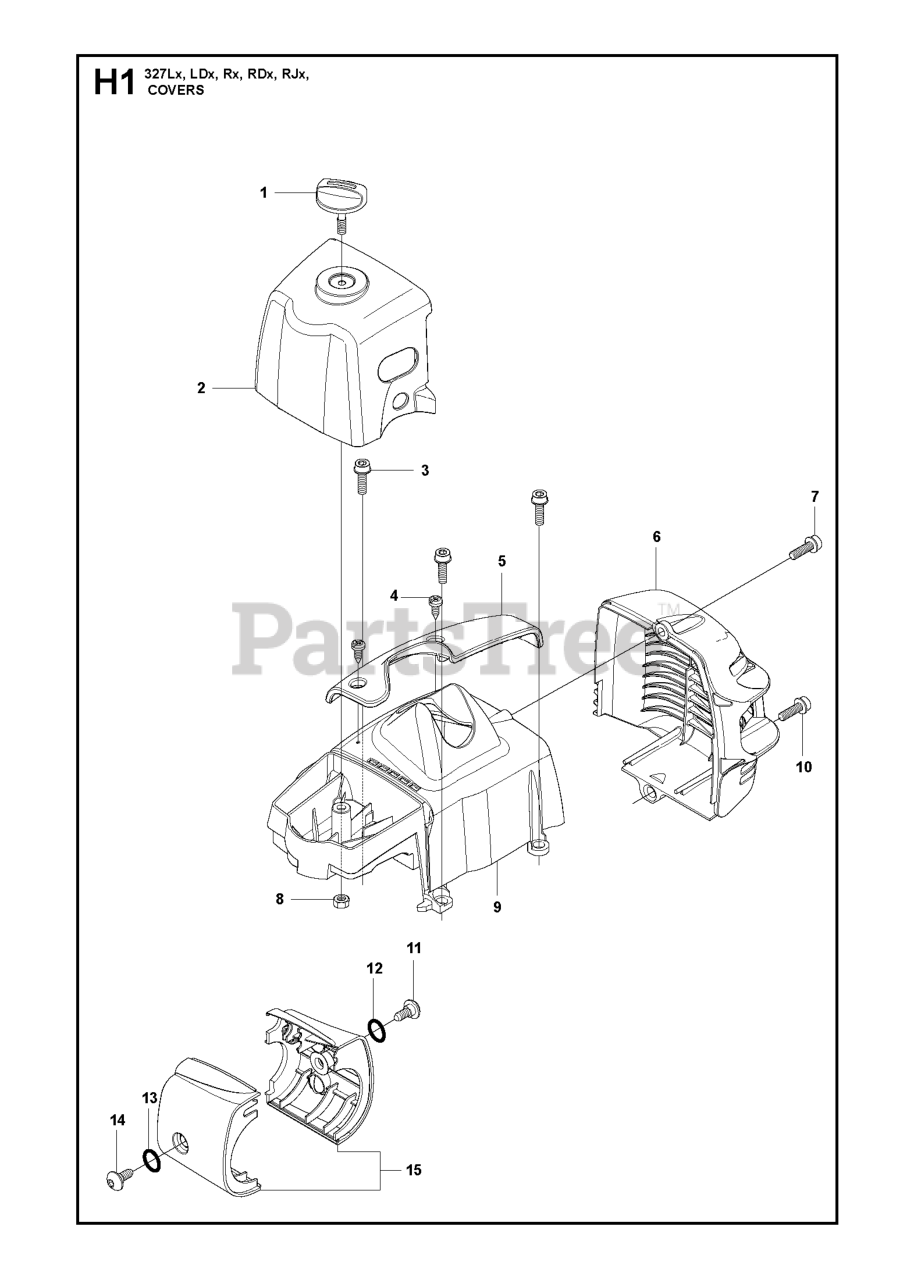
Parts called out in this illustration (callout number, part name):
2	FILTER COVER
3	SCREW
5	ARM PROTECTION
6	RP HEAT PROTECTOR
7	SCREW
9	RP CYLINDER COVER
11	SCREW MT5X11
12	O-RING 8X1.6
13	O-RING 8X1.6
14	SCREW MT5X11
